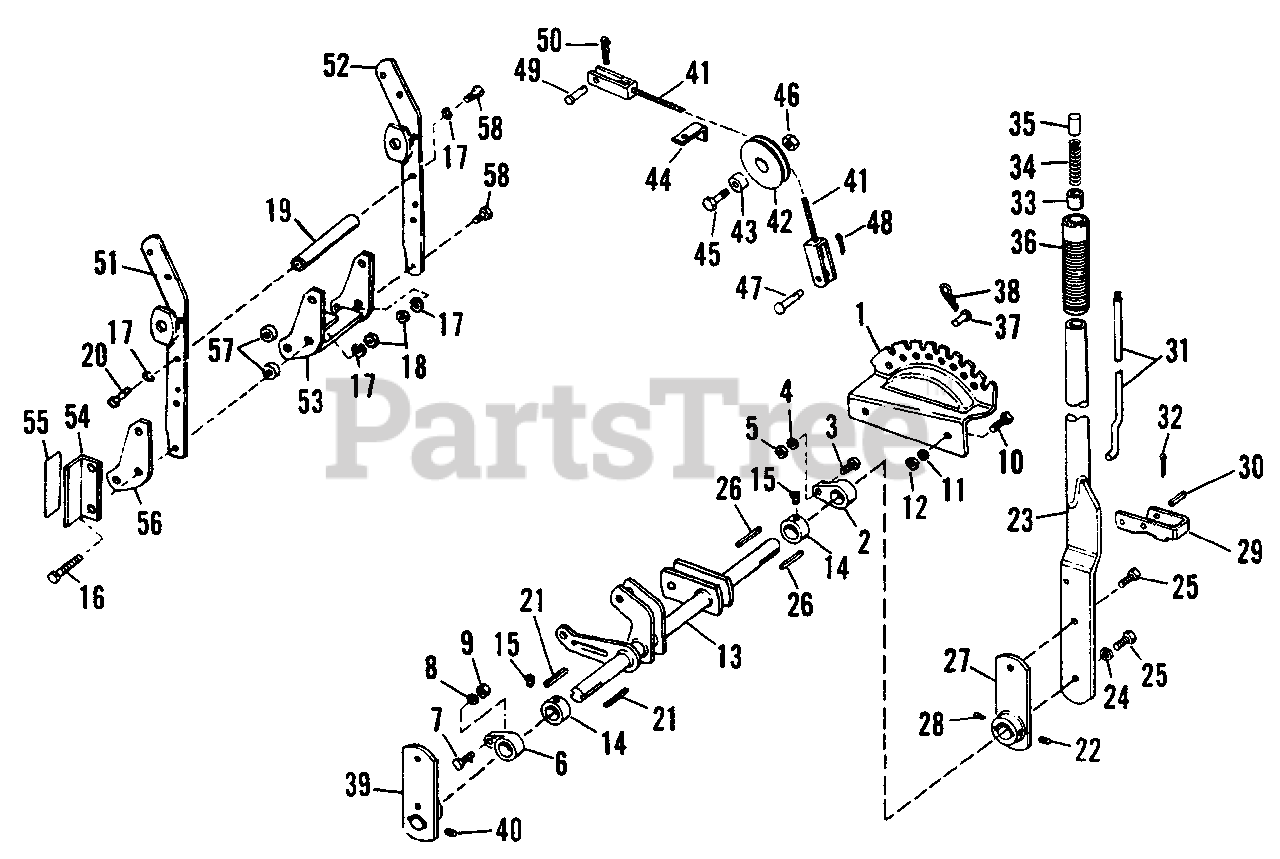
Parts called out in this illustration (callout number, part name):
1	Lift Lever Quadrant
2	Lift Lever Bearing
3	Hex Capscrew, 5/16"-18 x 1-1/4"
4	Lockwasher, 5/16"
5	Full Hex Nut, 5/16"-18
6	Lift Lever Bearing
7	Hex Capscrew, 5/16"-18 x 1-1/4"
8	Lockwasher, 5/16"
9	Hex Nut, 5/16"-18
10	Hex Capscrew, 3/8"-16 x 3/4"
11	Lockwasher, 3/8"
12	Full Hex Nut, 3/8"
13	Lift Shaft Assembly
14	Set Collar
15	Set Screw Sq. Hd., 5/16"-18 x 3/8"
16	Hex Capscrew, 7/16"-14 x 2-1/2"
17	Lockwasher, 7/16"
18	Full Hex Nut, 7/16"-14
20	Hex Capscrew, 7/16"-14 x 1-3/4"
22	Set Screw, 5/16"-18 x 1/4"
23	Lift Lever Assembly
24	Lockwasher, 3/8"
25	Hex Capscrew, 3/8"-16 x 1"
27	Lift Lever Assy. Inner Section
28	Set Screw, 5/16"-18 x 1/4"
29	Lift Lever Latch
30	Roll Pin, 3/8" x 1-1/4"
31	Latch Rod
32	Cotter Pin, 3/32" x 3/4"
35	Thumb Button
36	Handle Grip
38	Spring Clip
39	Front Lift Lever Assembly
40	Set Screw, 5/16"-18 x 1/4"
41	Cable Assy., Lift
44	Cable Guard
46	Hex Jam Lock Nut, 3/8"-16
47	Pin
48	Cotter Pin, 3/32" x 7/8"
50	Spring Clip
51	Arm Assembly
52	Arm Assembly
53	Draw Bar Assembly
54	Plate, Decal
55	Film, Shift
58	Hex Capscrew, 7/16"-14 x 1-1/4"
